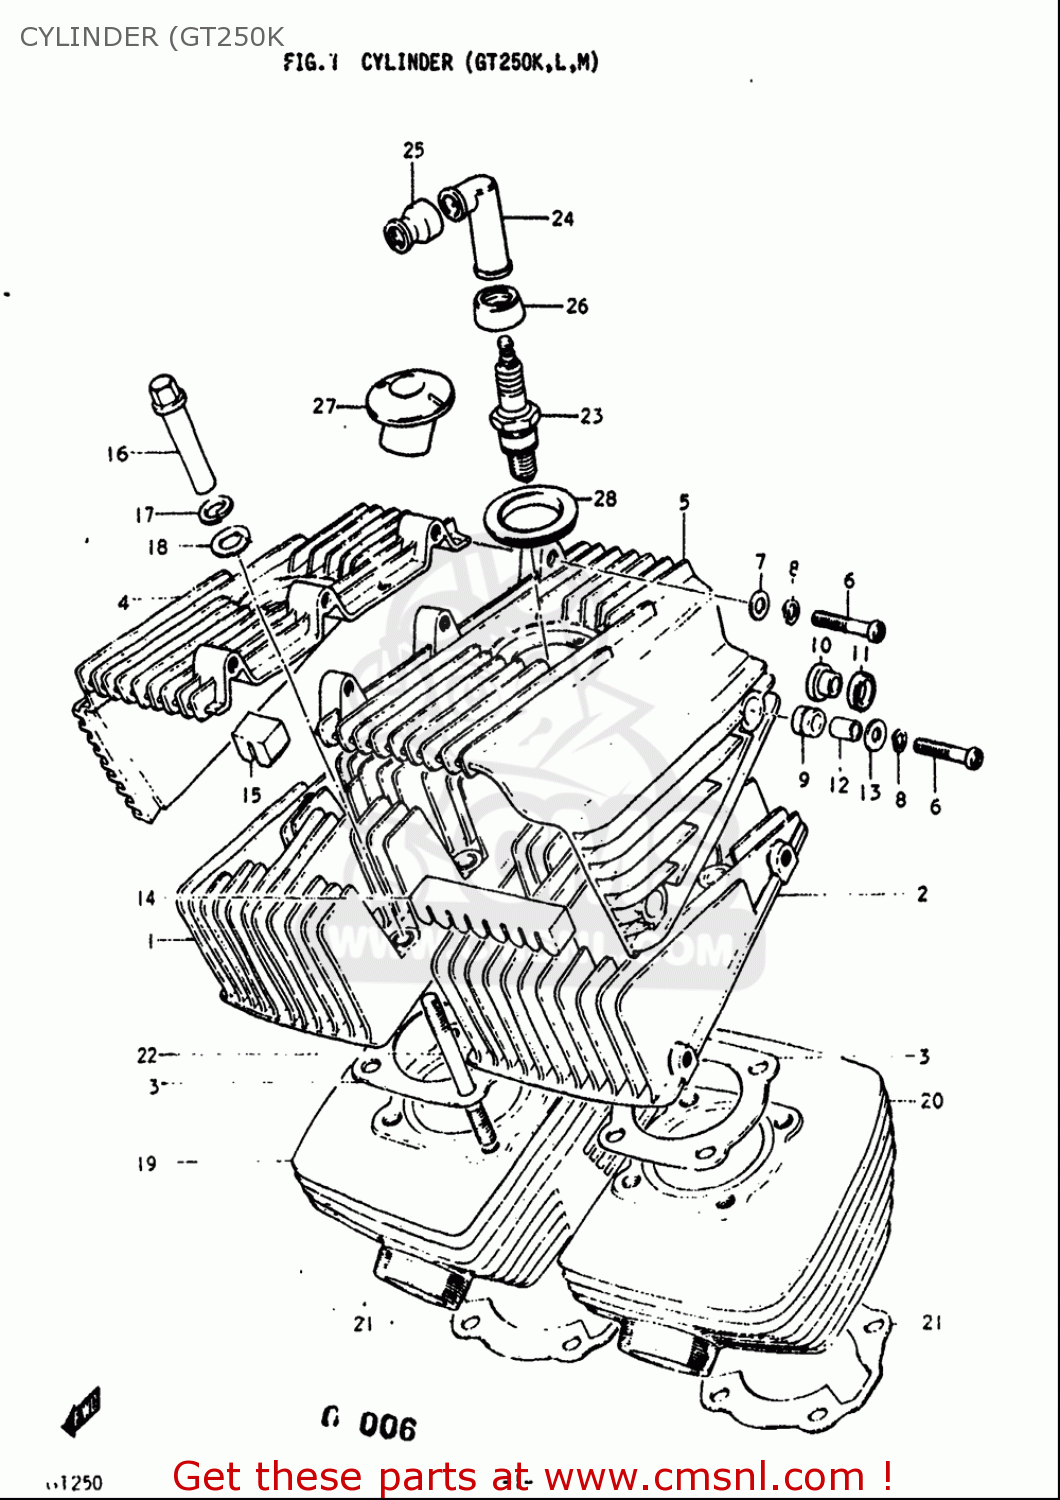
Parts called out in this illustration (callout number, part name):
3	GASKET,CYLINDER HEAD (NAS)
6	SCREW
7	WASHER
8	WASHER,LOCK
9	CUSHION
12	SPACER(6.1X8X12)
13	WASHER(6.5X14X1.6)
16	NUT (8MM)
17	WASHER,LOCK
18	WASHER
21	GASKET,CYLINDER (NAS)
22	BOLT,STUD
23	PLUG,SPARK
24	CAP, SPARK PLUG
25	SEAL,HIGH TENSION CORD
26	SEAL,SPARK PLUG
28	RING, SPARK PLUG
